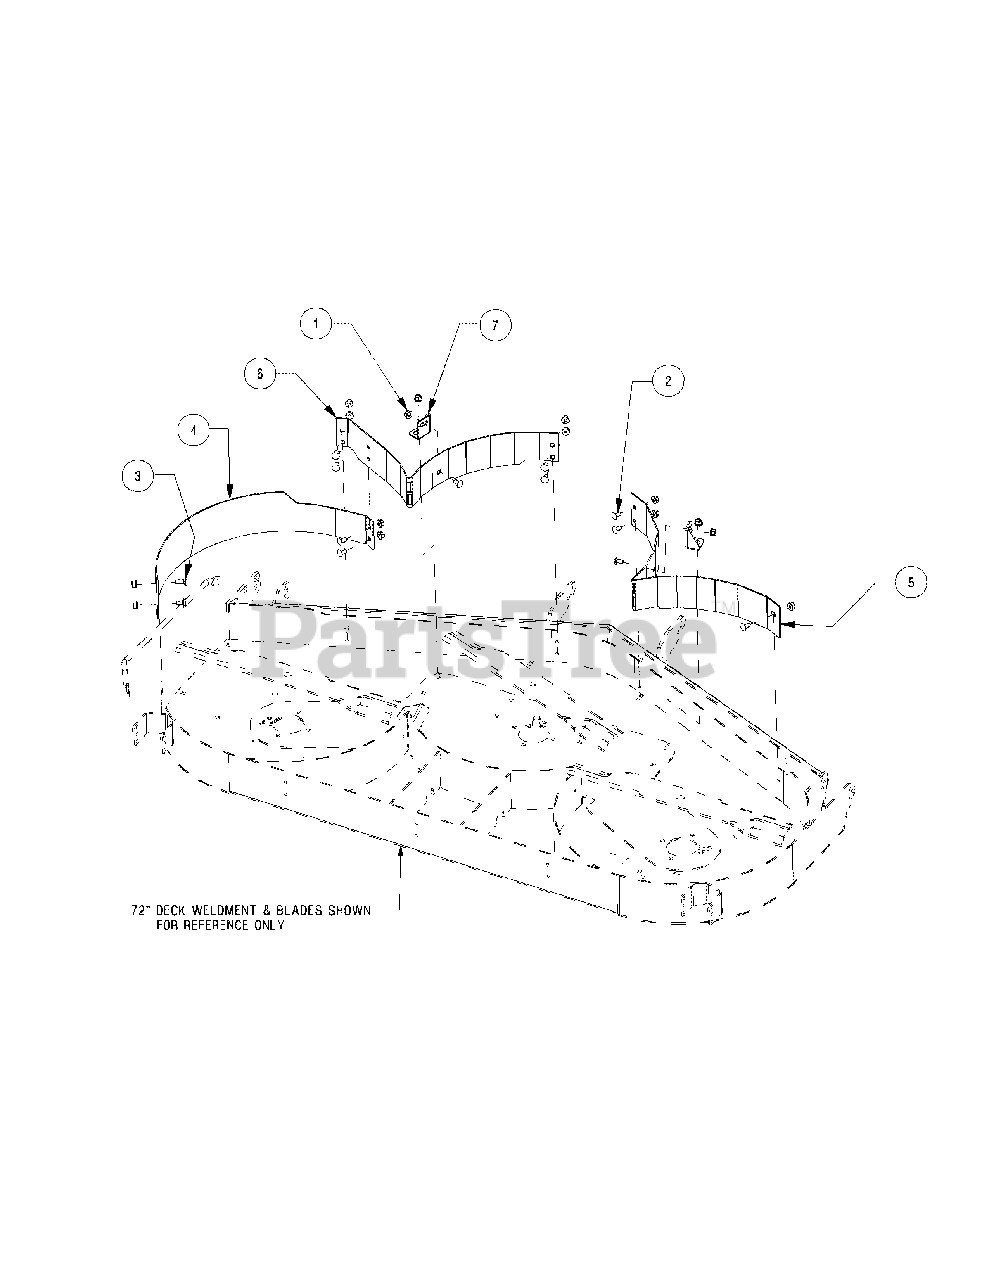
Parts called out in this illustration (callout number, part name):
1	Hex Nut, 3/8-16 Flange Lock
2	Carriage Bolt, 3/8-16 x .75 Long
3	Carriage Bolt, 3/8-16 x 1.00 Long
4	Baffle Mulch Fab 72 RH
5	Baffle Mulch Fab 72 LH
6	Baffle Mulch Fab 72 Center
7	Support Bracket
